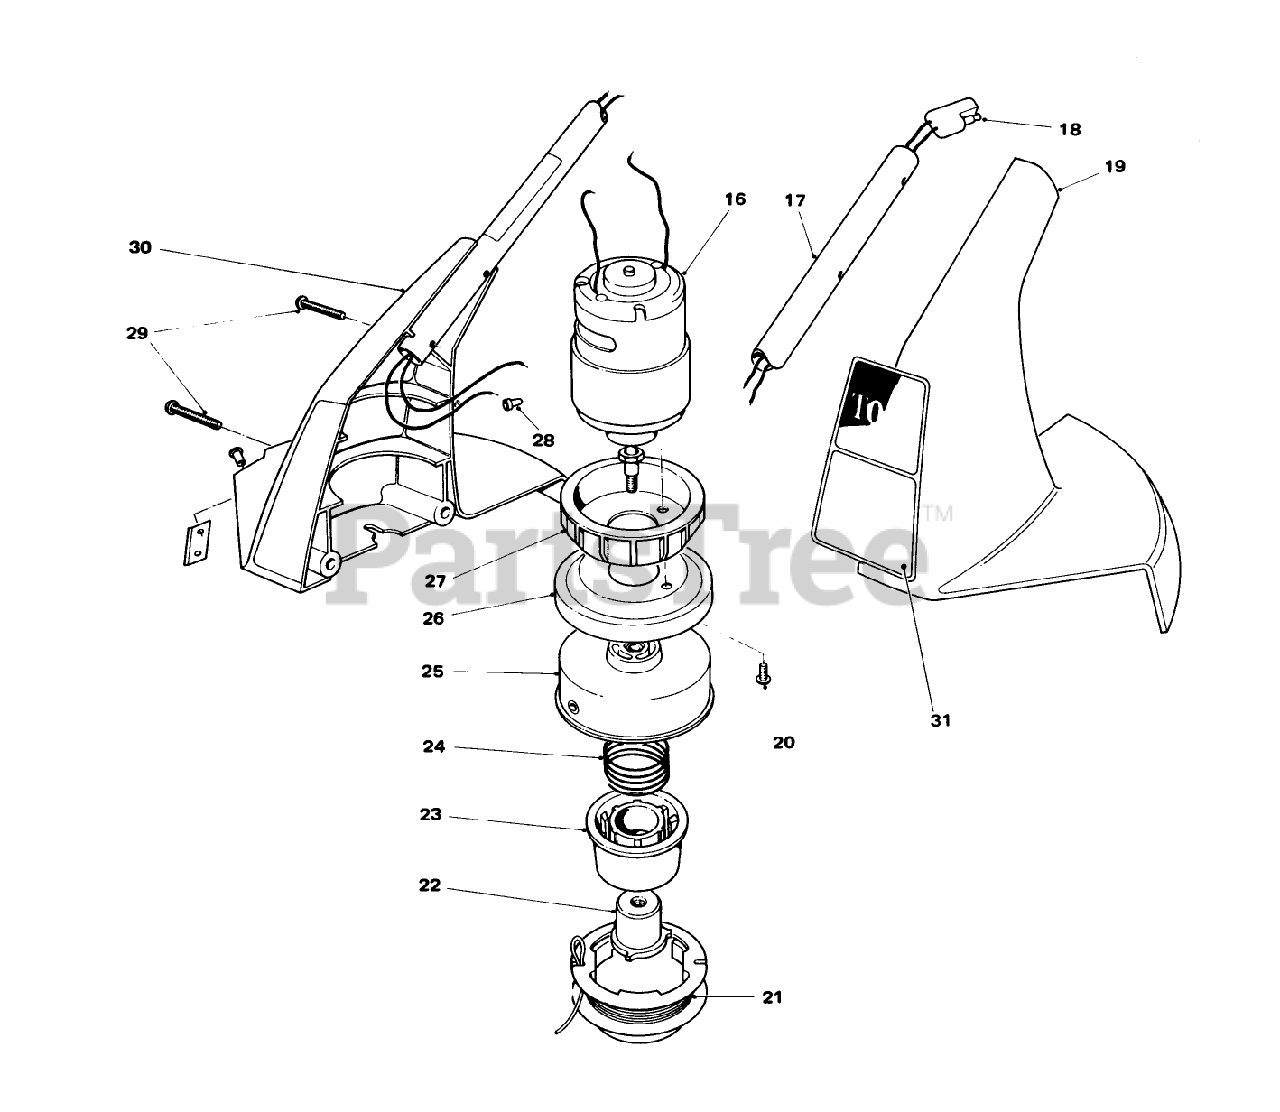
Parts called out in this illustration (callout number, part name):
22	DRIVER
23	CORE - SPOOL
29	SCREW-PLASTITE
